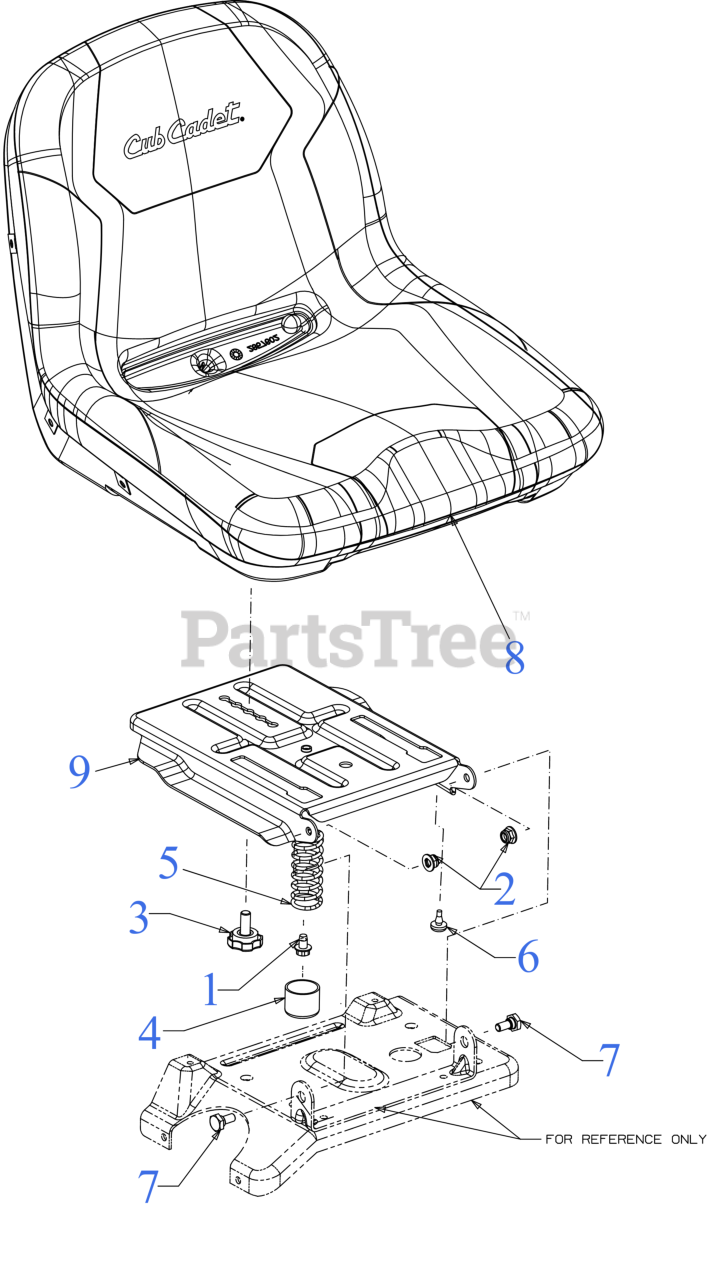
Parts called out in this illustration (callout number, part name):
1	SCREW 5/16-18 x .500
2	FLANGE LOCK NUT 5/16-18
3	SEAT ADJUSTMENT KNOB
4	SEAT SPRING CAP
5	SEAT SPRING
6	RUBBER BUMPER
7	SHOULDER SCREW .437
8	SEAT (HI BACK/ARM OPT)
9	MANUAL SEAT ADJUSTMENT BRACKET
